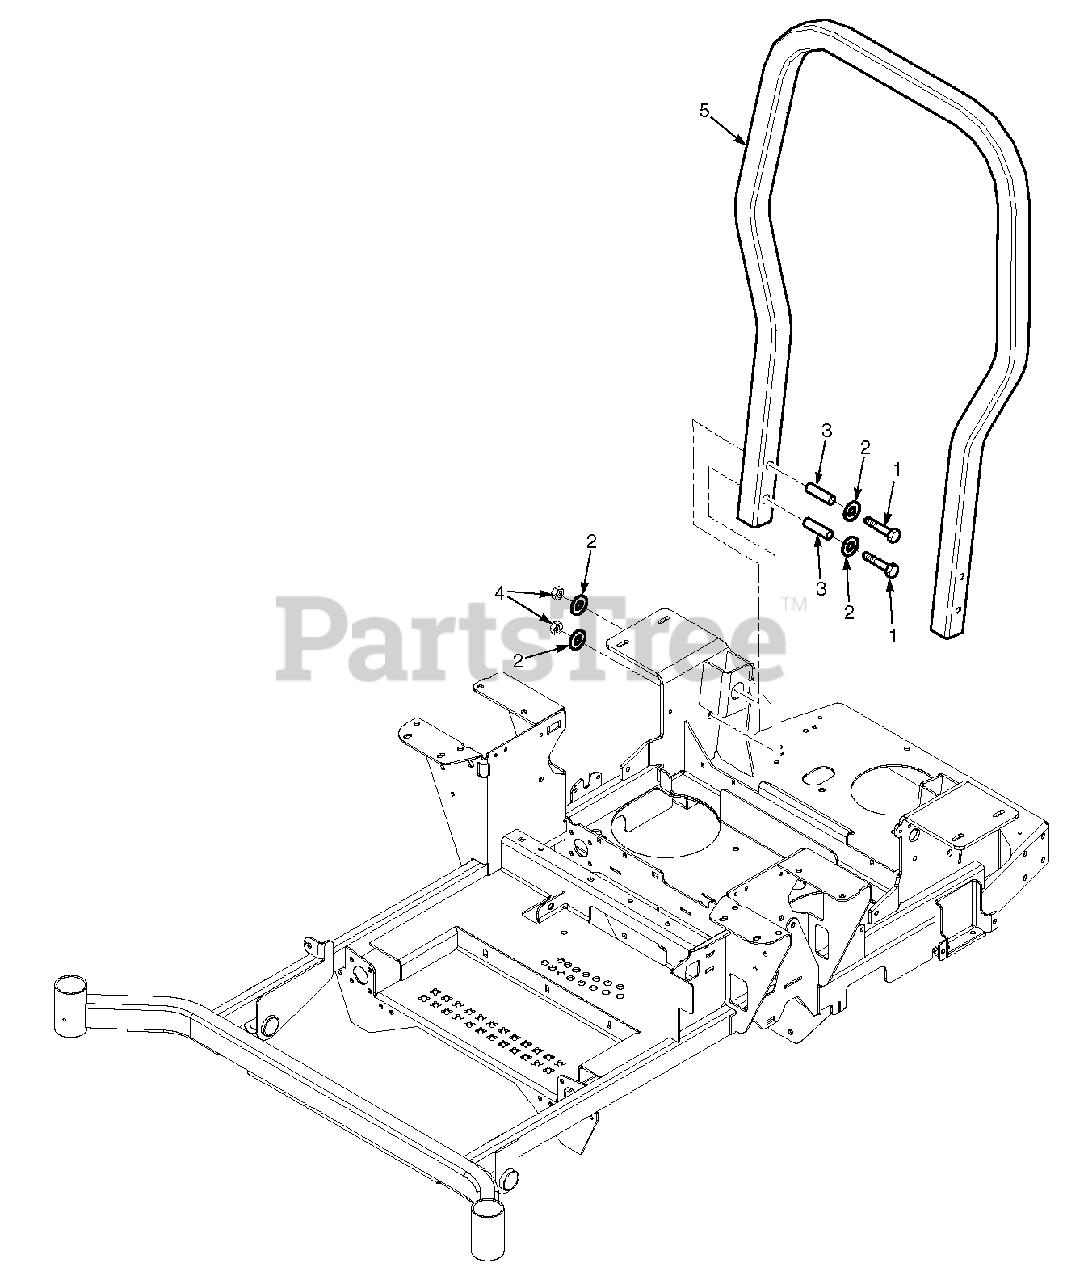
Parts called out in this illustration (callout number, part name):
1	Bolt, Hex Head 1/213 x 3" Gr. 8
2	Flatwasher, 1/2 - .531 x 1.062 x .095
3	Bushing, SFZ ROPS
4	Nut, Center Lock 1/2-13
